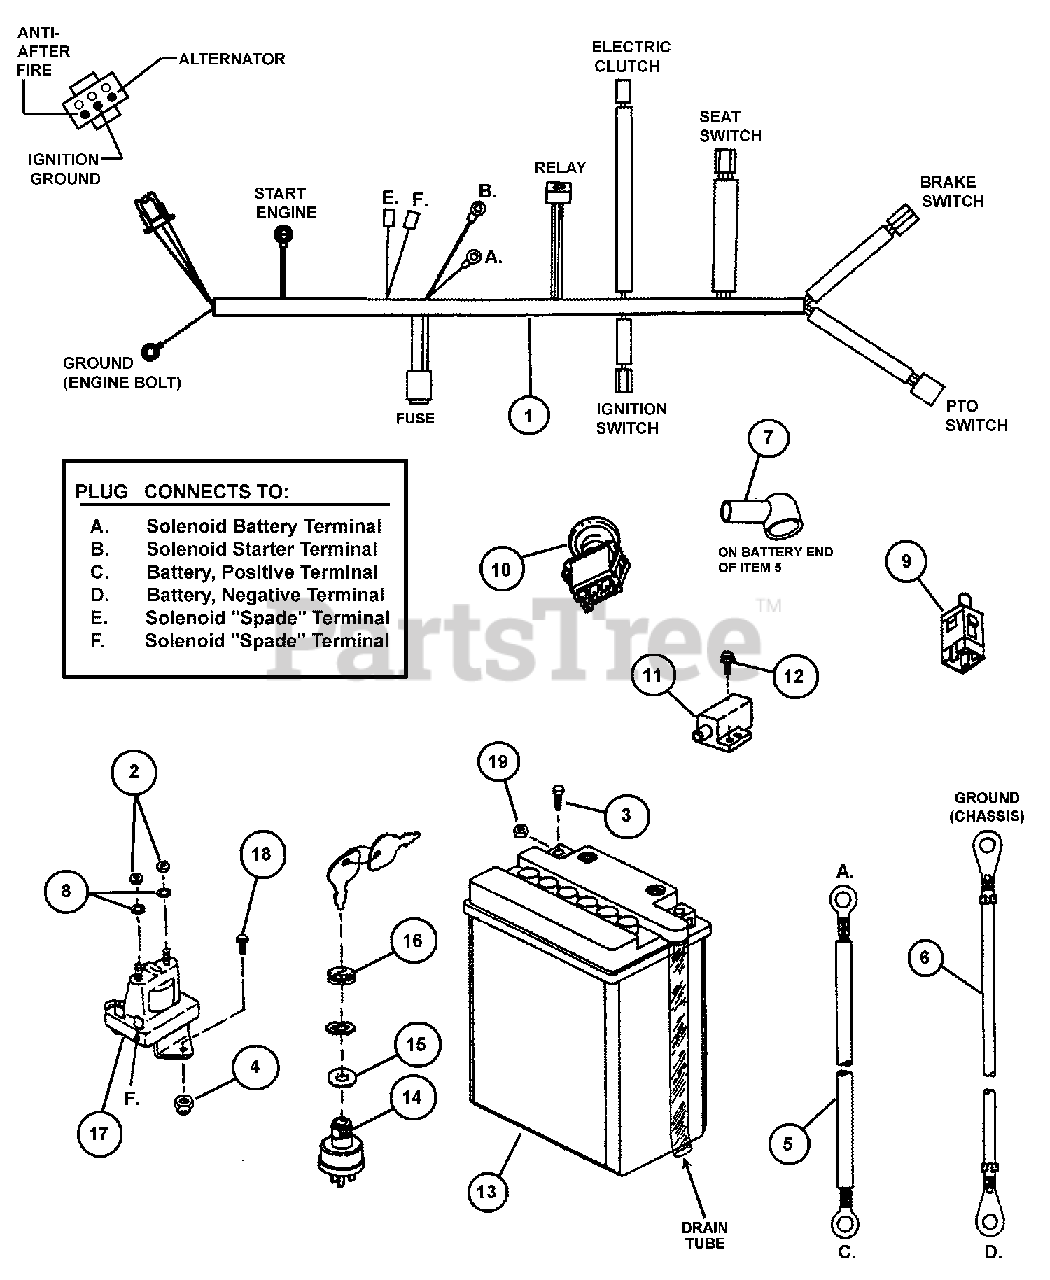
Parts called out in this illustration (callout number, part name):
1	WIRING HARNESS, 18 HP Briggs
2	NUT, 1/4-20 Hex Jam, GR5 or B
3	SCREW, #10-24 x 1/2" Hex Head Cap
4	NUT, 1/4-20 Hex Flange Lock
5	WIRE, Positive, 13" long
6	WIRE, Negative, 14" long
7	COVER, Battery Cable
8	WASHER, 1/4" Internal Tooth Lock
9	SWITCH, Seat (NO/NC) Snap-In
10	SWITCH, PTO E.C.
11	SWITCH, Park Brake (NC/NO)
12	SCREW, #10-24 x 1/2" Hex Washer Self-Tap (Torx)
13	BATTERY, 12V, 3 Amp, 190 Cold Cranking Amp
14	SWITCH, Ignition (After-fire Solenoid)
15	SPACER, .65 x .88 x .10 - YZ
16	BEZEL
17	SOLENOID - Super Trombetta- 2 Terminal
18	SCREW, 1/4-20 x 1/2" Hex Head Cap, GR5
19	NUT, #10-24 Hex Twin "Whiz" Lock
